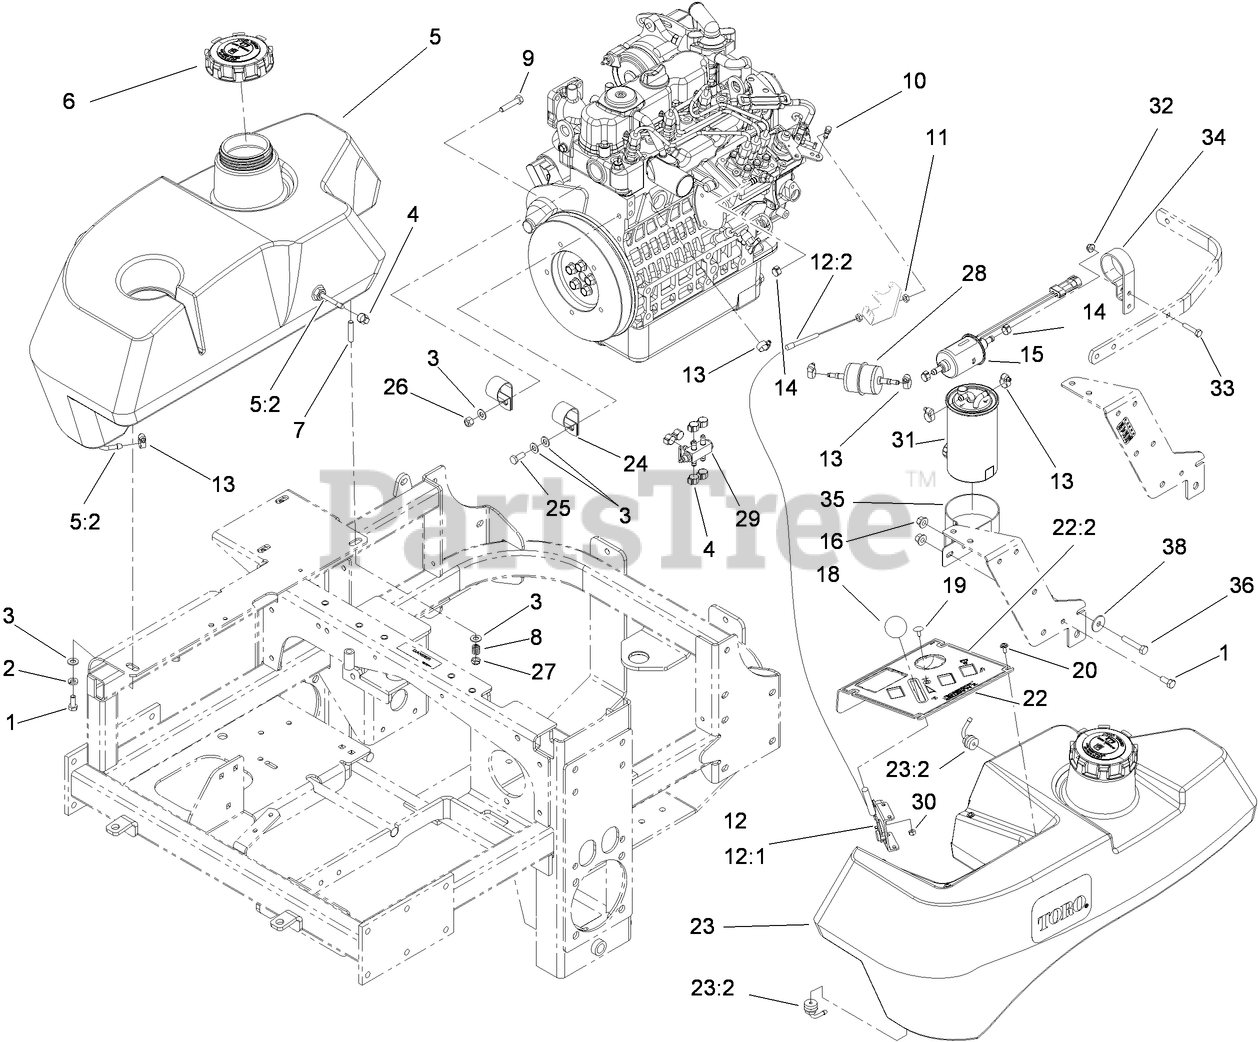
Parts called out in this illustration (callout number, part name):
1	SCREW-HH
2	WASHER-LOCK
3	WASHER-PLAIN
4	CLAMP-HOSE, FUEL
5	RH FUEL TANK ASM
5:2	Fitting-Fuel, Bulkhead
6	CAP-BIODIESEL
8	SPRING-TANK, FUEL
9	SCREW-HH
10	SWIVEL-STOP, CABLE
11	NUT-JAM
12	CABLE-CONTROL, THROTTLE
12:1	LEVER-CABLE, THROTTLE
12:2	CABLE-THROTTLE
13	CLAMP-WORM
14	CLAMP-HOSE, FUEL
15	PUMP-FUEL
16	NUT-LOCK, NI
18	KNOB-BALL
19	BOLT-CARR
20	SCREW-PPH
22	CONTROL PANEL ASM
22:2	DECAL-PANEL, CONTROL
23	LH FUEL TANK ASM
23:2	Fitting-Fuel, Bulkhead
24	CLIP-LOOM
25	SCREW-HH
26	NUT-LOCK, NI
27	NUT-LOCK, NI
28	FILTER-INLINE
29	VALVE-FUEL, DUAL FLOW
30	NUT-LOCK, NI
31	ELEMENT-FILTER, FUEL/WATER
32	NUT-HF
33	SCREW-HH
34	BRACKET-PUMP, FUEL
35	BRACKET-FILTER, FUEL
36	SCREW-HH
38	WASHER-FLAT
